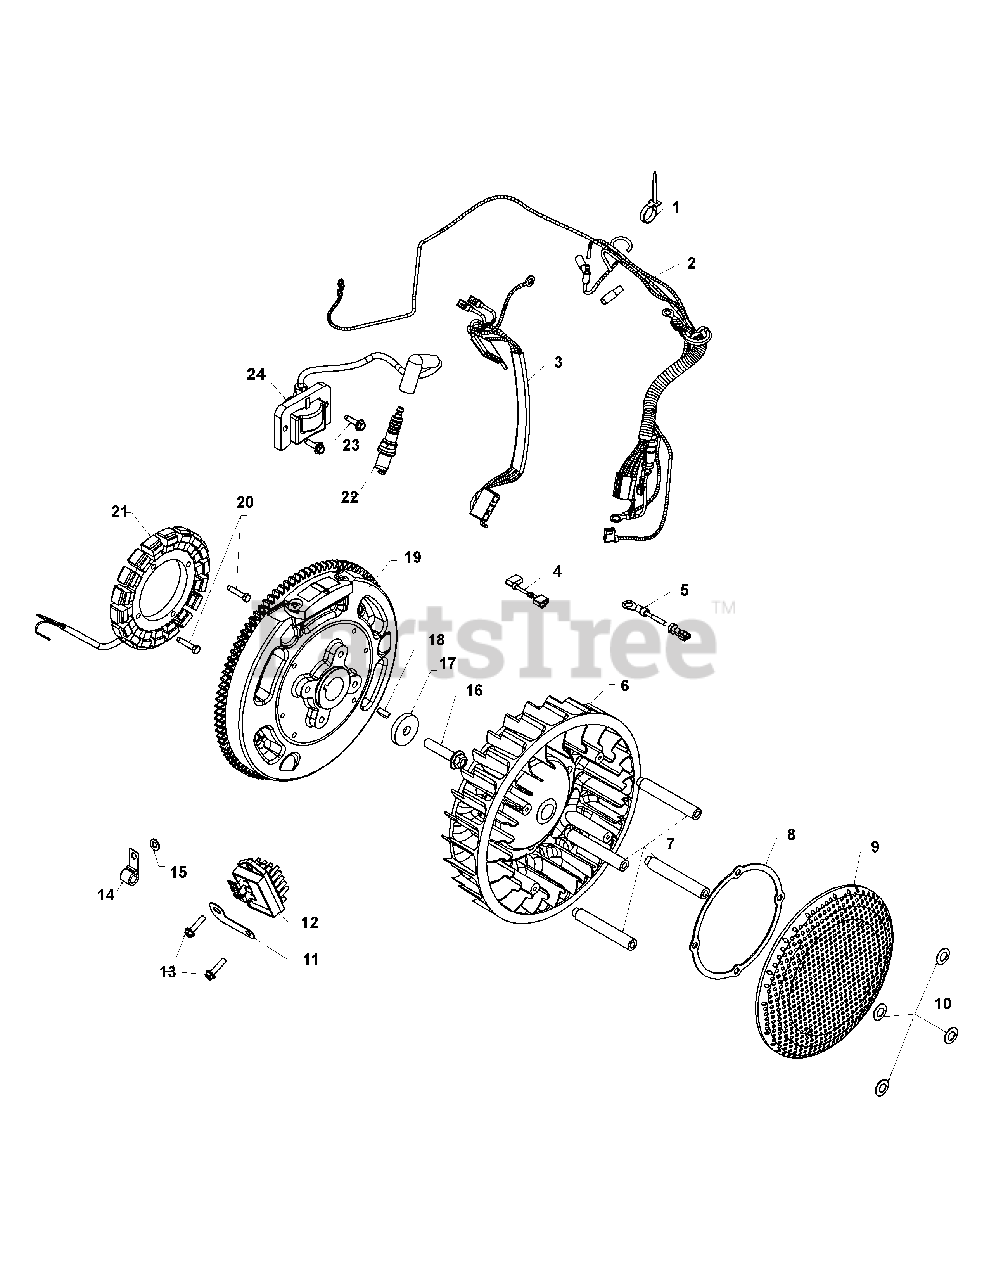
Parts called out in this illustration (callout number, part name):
2	Wiring Harness
3	DSAI Wiring Harness
4	Oil Sentry Lead
10	Spring Washer, 10 mm
11	Ground Strap Bracket
12	Rectifier Regulator
13	Hi-Lo Hex Flange Screw
15	Flat Washer, 1/4
16	Flange Screw, M10 x 1.5 x 45
17	Flat Washer, 13/32
18	Key, 3/16 x 5/8
20	Screw, M5 x 0.8 x 25
21	15 Amp Stator Kit
23	Flange Screw, M5 x 0.8 x 20
24	Spark Module (DSAI) Assembly
